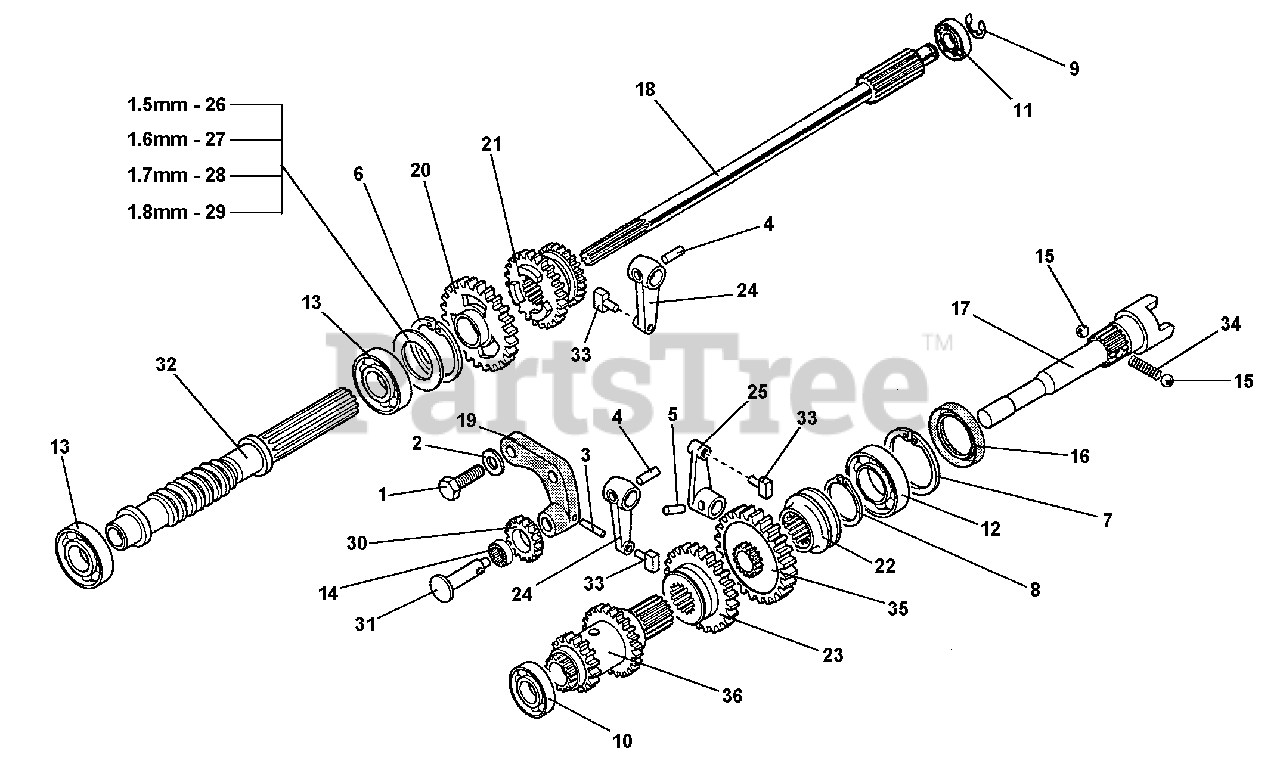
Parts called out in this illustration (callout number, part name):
1	SCREW M10X30
2	SUPER WASHER 10
3	LOCKING PIN, 4X24 SPIRAL
4	LOCKING PIN, 6X24 SPIRAL
5	LOCKING PIN, 6X20 SPIRAL
6	CIRCLIP, INTERNAL
7	CIRCLIP, INTERNAL
8	CIRCLIP, EXTERNAL
9	RETAINING RING
10	BEARING, 15X35X11
11	BEARING, 15X42X13
12	BEARING, 30X55X13
13	BEARING, 25X52X15
14	BEARING, 12X15X10
16	OIL SEAL, 38X55X7
18	MAIN DRIVE SHAFT
19	REVERSER BRACKET
21	DOUBLE SLIDER
23	SLIDER, REVERSER
24	LEVER, REVERSER
25	LEVER, PTO ENGAGMENT
26	SHIM, 1.5MM
27	SHIM, 1.6MM
30	REVERSE GEAR
31	PIN, REVERSE GEAR
34	SPRING, PTO BALLS
36	SECOND GEAR
